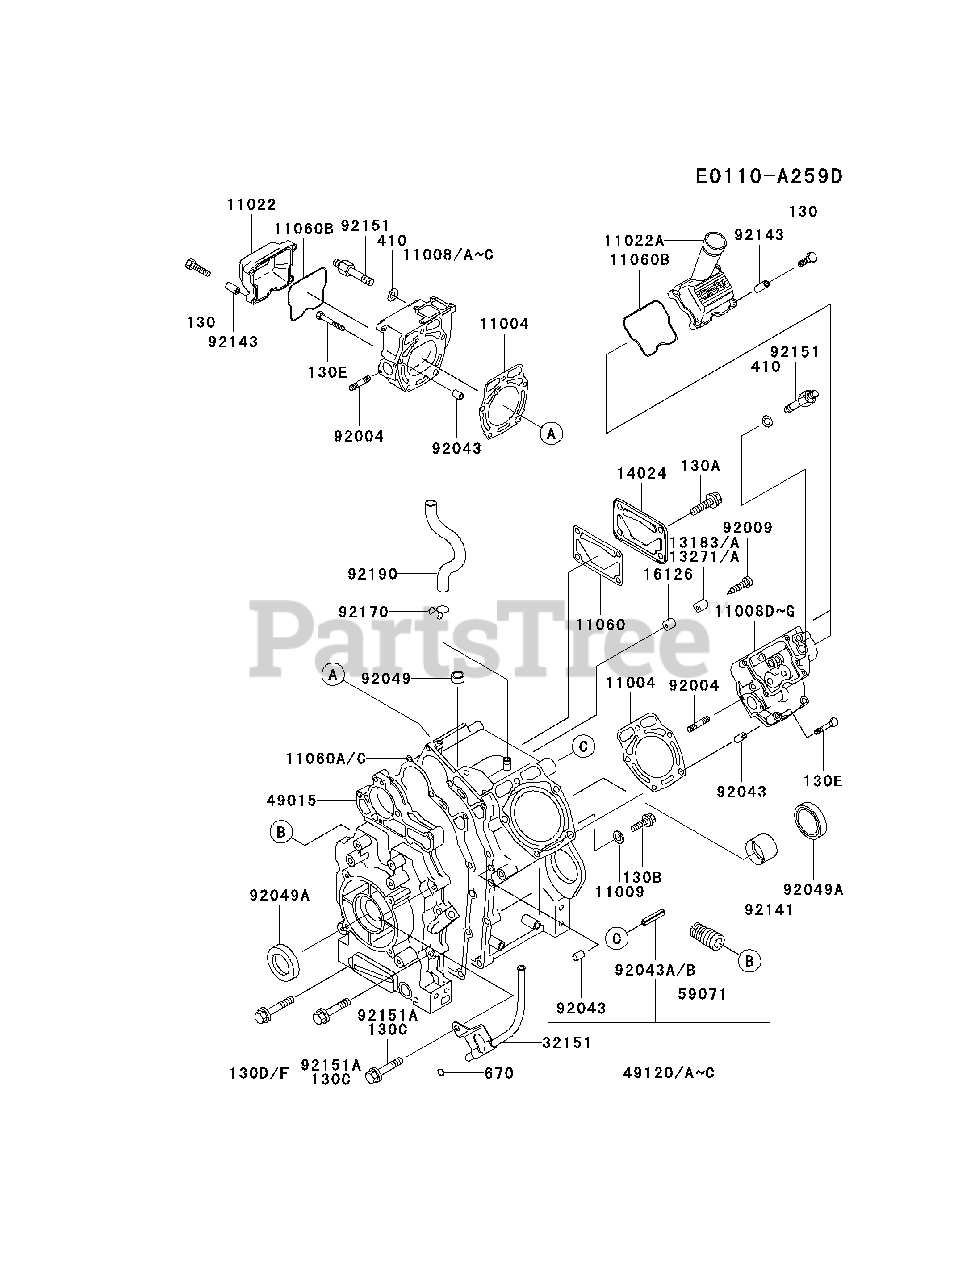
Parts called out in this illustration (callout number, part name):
130	BOLT-FLANGED
130A	BOLT-FLANGED
130B	BOLT-FLANGED
130C	BOLT-FLANGED
130D	BOLT-FLANGED
130E	BOLT-FLANGED
410	W-PLAIN-S
